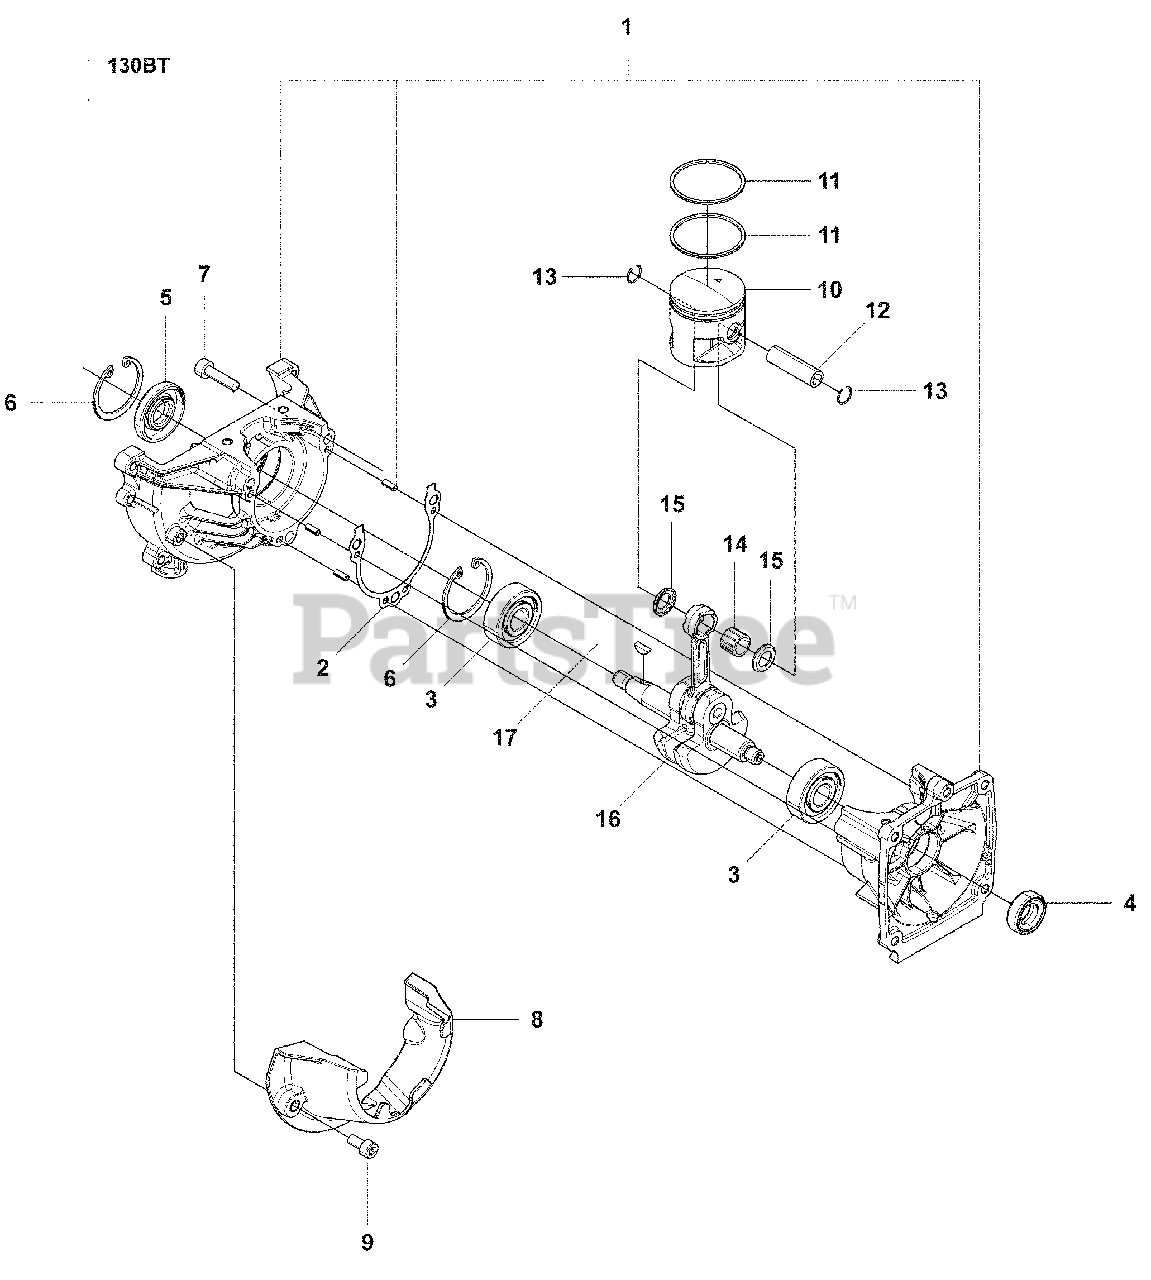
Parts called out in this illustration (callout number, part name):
1	CRANKCASE-C
2	Case Gasket
5	Seal
7	Torx Bolt
8	Case Cover
9	Bolt, 8
10	Piston
16	Crankshaft, Comp
17	Flywheel Key
